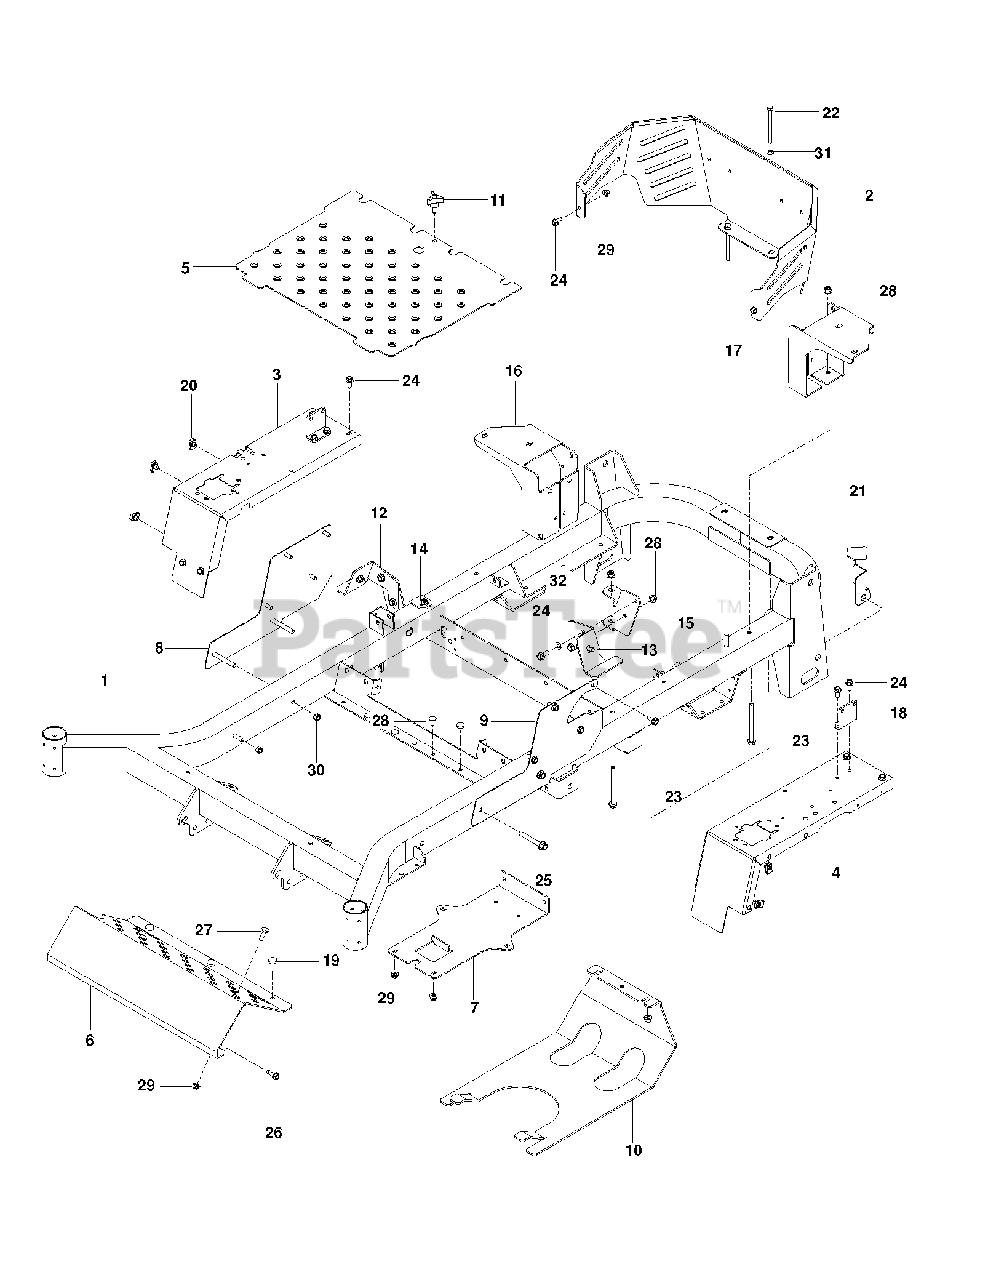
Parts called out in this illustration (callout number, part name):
5	FLOOR PAN W/DECALS
6	PLATE, FOOT REST - RAM DK BLUE
7	PLATE, BATTERY, BLACK
8	SIDE, RT, BL
9	SIDE, LT, BL
10	GUARD, SKID, BLUE
11	KNOB W/STUD
12	MOUNT, TANK, RT-BLK
13	MOUNT, TANK, LT-BLK
14	SUPPORT FRONT TANK R BLK
15	SUPPORT FRONT TANK L BLK
16	SUPPORT REAR TANK R BLK
17	SUPPORT REAR TANK L BLK
19	GROMMET, BUMPER
20	U-CLIP 5/16-18 NUT RETAINER
22	HCS 5/16C X 4
23	HHFS 5/16-18 X 3 3/4
24	HHFS 5/16-18 X 3/4
25	HHFS 3/8-16 X 2 3/4
27	RHSNB 5/16C X 1
28	BOLT 5/16C X 3/4" CARRIAGE
29	5/16-18 NYLOC FLANGE NUT
30	NUT HEX 3/8-16 NYLON, THIN
31	FLAT WASHER 5/16 SAE
32	WASH 5/16 DISC SPRING ZD
